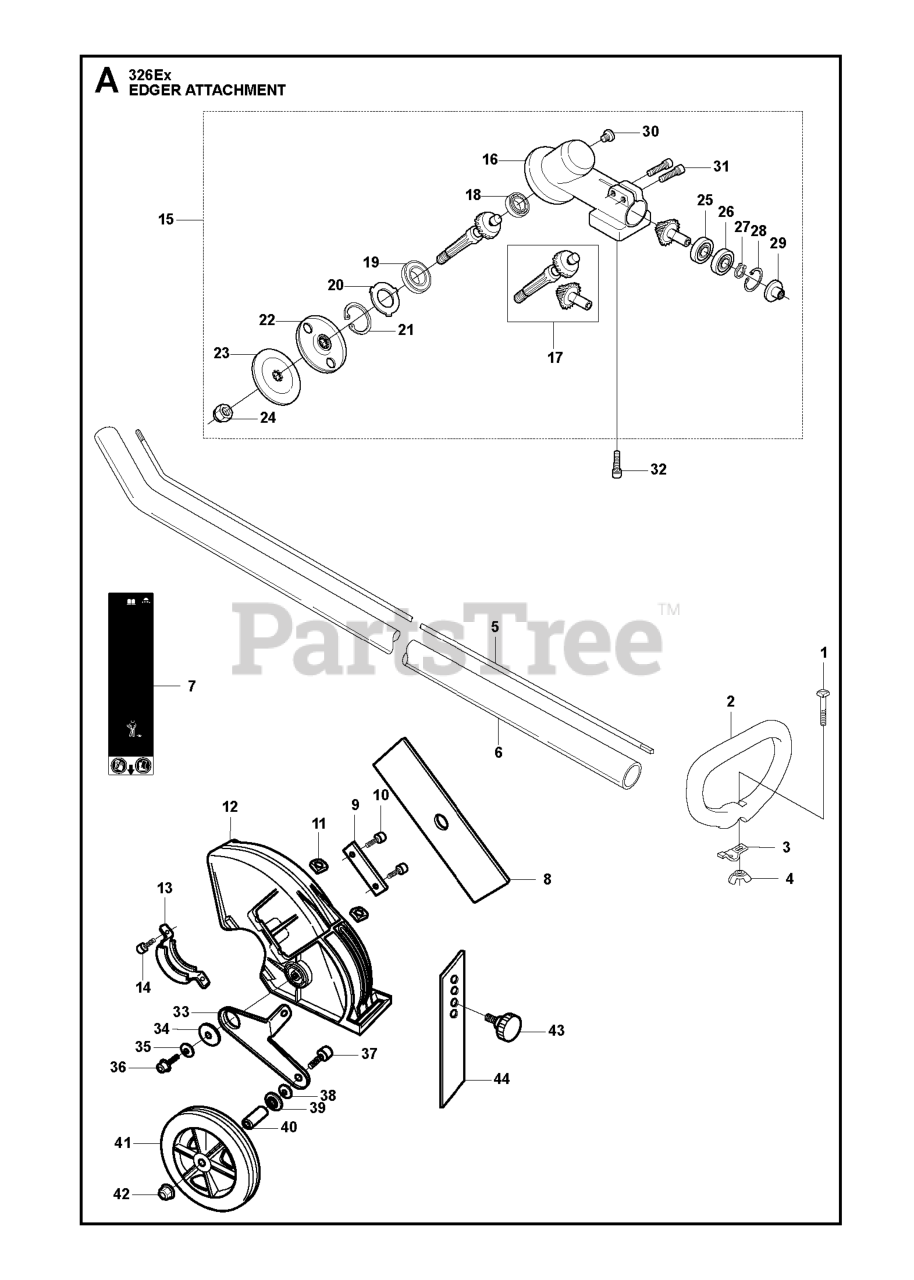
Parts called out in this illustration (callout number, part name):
2	HANDLE, LOOP
3	HOLDER
5	SHAFT
6	PIPE
7	DECAL, SAFETY
8	BLADE 7.52X2X.125
12	BLADE PROTECTOR
15	ANGLE GEAR
16	GEAR HOUSING
18	BALL BEARING 24X9X1/609ZR
19	BALL BEARING 6201-2RS1
21	RETAINING RING
24	GEARHEAD NUT - BRUSHCUTTER
25	BALL BEARING 24X9X1/609ZR
26	BALL BEARING 609Z
27	RETAINING RING
28	RETAINING RING
36	SCREW
38	WASHER BRB 8.4X17
41	WHEEL, EDGER
42	NUT M8 FLANGE
44	RUBBER PROTECTOR, EDGER
